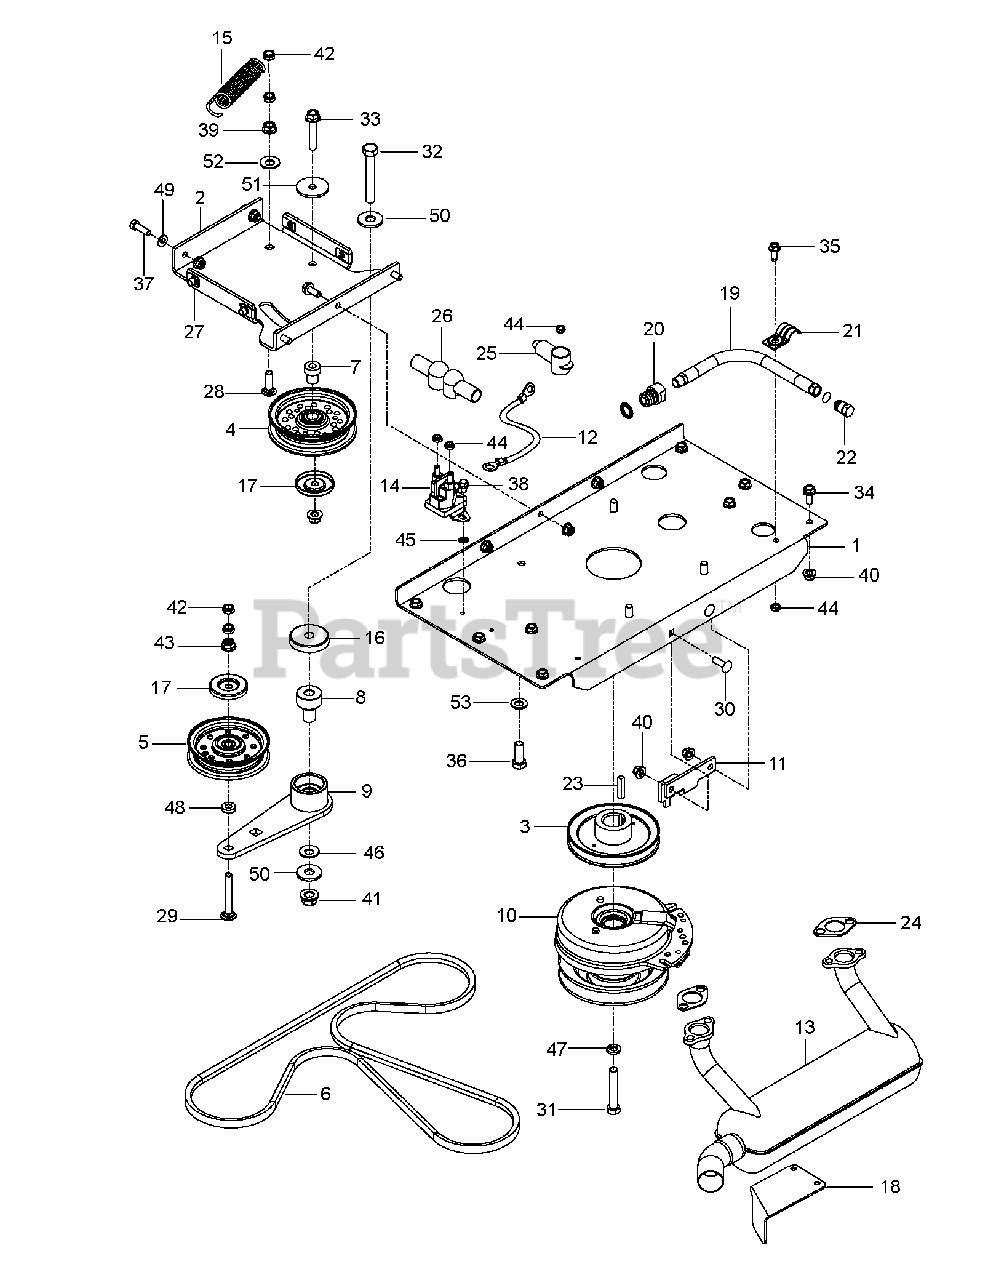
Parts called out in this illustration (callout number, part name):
1	PLATE.PNT.ENGINE.E-DIP
2	PLATE, IDLER, BLK
3	PULLEY, V, 1.125 BORE
4	IDLER PULLEY
5	PULLEY.IDLER.FLAT.46.PR.DR.
6	BELT, HYDRO, 3400
7	PIVOT, IDLER
8	PIVOT, BEARING
9	ARM, IDLER, STEEL, W/BGS
10	CLUTCH 200 FT LB
11	STOP, CLUTCH, BLACK
12	CABLE POSITIVE
13	MUFFLER.26HP.KAW.FX651V-730V
14	SOLENOID.W/BRASS.PLUNGER
15	SPRING, PUMP
16	SHIELD, DUST
17	DUST SHIELD
18	SHIELD MUFFLER
19	HOSE.ASSEMBLY.OIL.DRAIN
20	ADAPTER, OIL DRAIN
22	PLUG OIL DRAIN
23	KEY, 1/4 SQ X 1 1/4
24	GASKET.EXHAUST.KAWASAKI
26	TERMINAL COVER
27	U-CLIP 5/16-18 NUT RETAINER
28	BOLT.3/8-14X1.25
29	BOLT
31	CLUTCH BOLT7/16-20X2.5 GR596HR
32	HCS 1/2-13 X 3-1/4 GD 5 ZD
33	HHFS 3/8-16 X 2.0 GD 5
34	HHFS 5/16-18 X 3/4
35	BOLT
37	BOLT.FIN.HEX.5/16-18UNC X 1.00
38	RP_SCREW.1/4-20X3/8
39	NUT 3/8C WHIZ
40	5/16-18 NYLOC FLANGE NUT
41	NUT, 1/2-13 HEX FLG NYLOC ZD
42	NUT HEX 3/8-16 NYLON, THIN
43	NUT 3/8-16 HEX FLG NYLOC ZD
44	JAM NUT 1/4C (2 2 PW01)
45	WASHER 1/4 INT TOOTH
46	CONTACT BELLSPR 1/2
47	WASHER 7/16 LOCK
48	WASHER 3/8 X 3/4 X .187 TK
49	WASHER
50	WASHER.9/16 X 1 3/8 X 12 GA.
51	WASHER, 3/8 SPEC
52	WASHER 3/8 FLAT
53	SLW 3/8 STD
